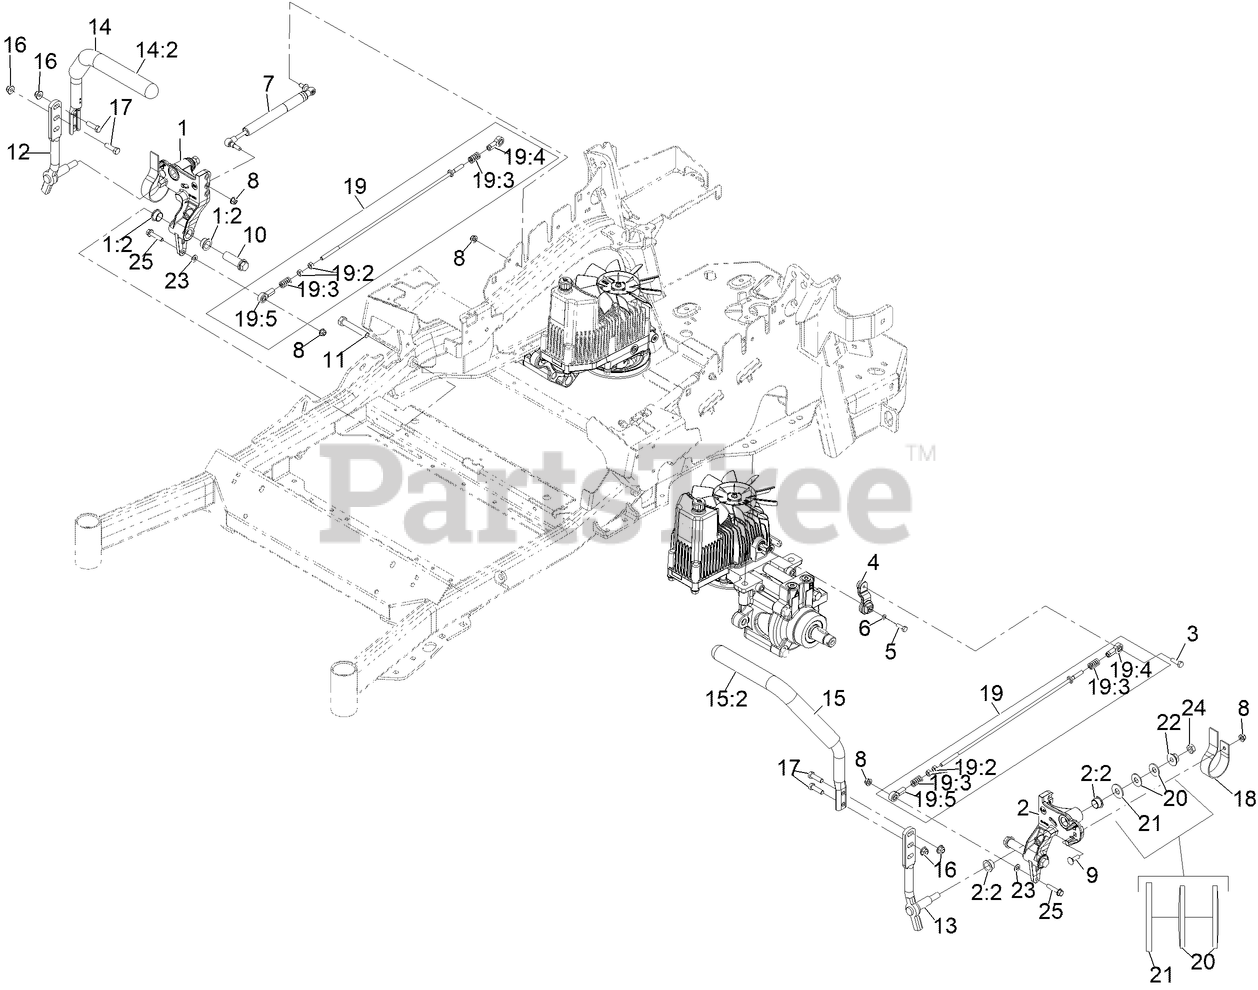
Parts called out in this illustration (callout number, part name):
1	RH MOTION CONTROL AND BUSHING ASM
1:2	BUSHING-FLANGE
2	LH MOTION CONTROL AND BUSHING ASM
2:2	BUSHING-FLANGE
3	SCREW-HH, THREAD LOCKING
4	ARM-CONTROL, PUMP
5	SCREW-HH
6	WASHER-SPRING
7	DAMPER, MOTION CONTROL
8	NUT-HF, NI
9	BOLT-CARR
10	HUB-THREADED
11	SCREW-HH
12	LEVER-CONTROL MOTION, RH
13	LEVER-CONTROL MOTION, LH
14	ASM-HANDLE-RH
14:2	GRIP-CONTROL, LEVER
15	LH HANDLE ASM
15:2	GRIP-CONTROL, LEVER
16	NUT-HF, NI
17	SCREW-HH
18	SPRING-LEAF
19	FRONT PUMP LINKAGE ASM
19:2	NUT-HEX
19:3	SPRING-COMPRESSION
19:4	BALLJOINT-LH
19:5	BALLJOINT-RH
20	WASHER-SPRING
21	WASHER-FLAT
22	NUT-HF
23	WASHER-PLAIN
24	NUT-JAM
25	SCREW-HHF
